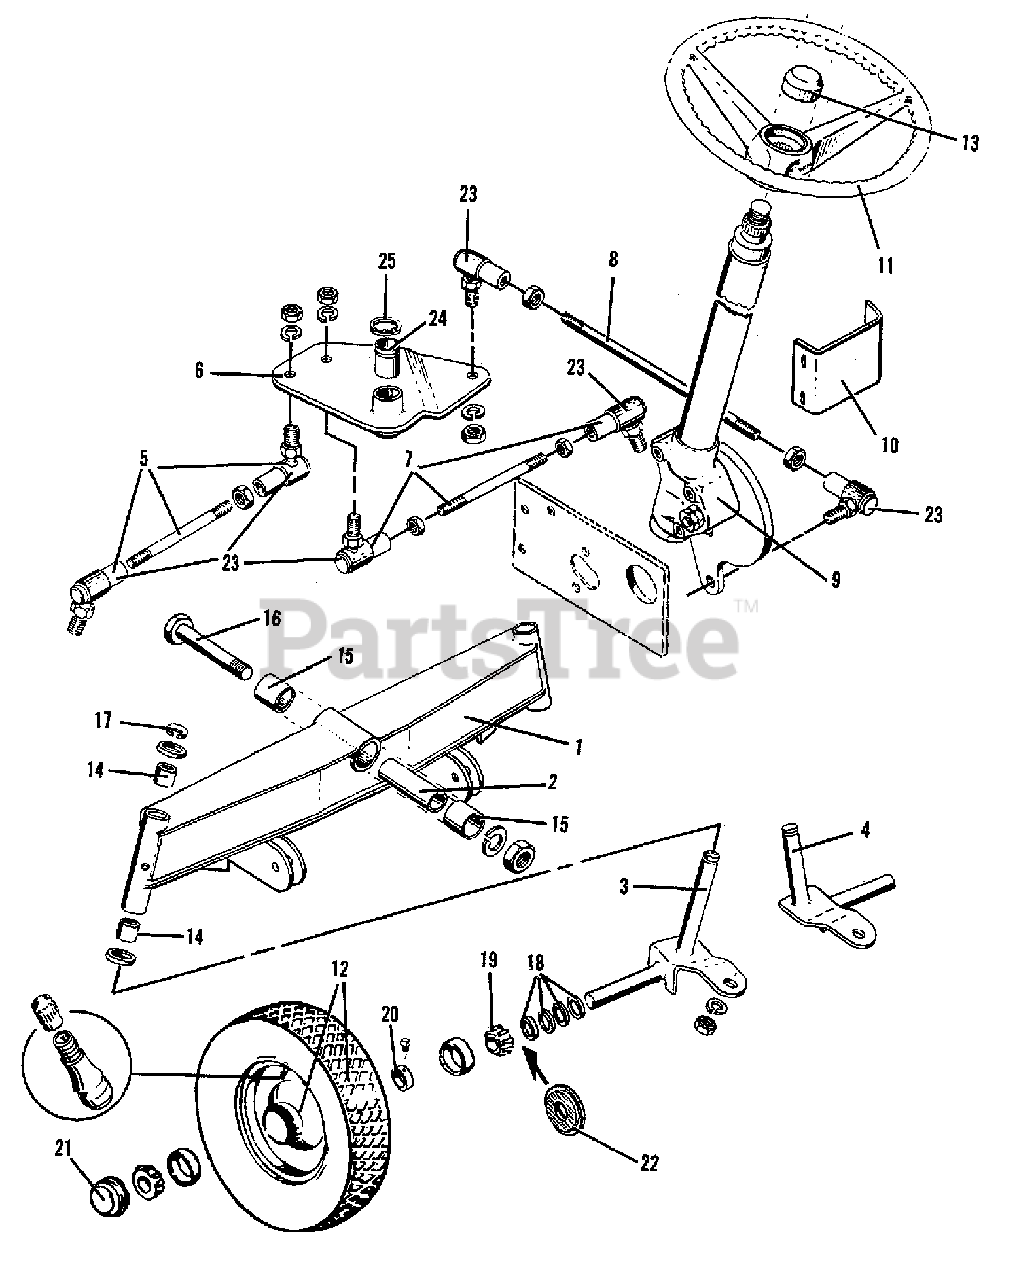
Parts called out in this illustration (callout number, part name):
1	AXLE ASSEMBLY, Front (Includes Item 15)
1	FITTING, Lube (Packaging Of 10)
2	SLEEVE, Axle
2	LOCKWASHER, 3/4
2	NUT, 3/4 NC
3	SPINDLE ASSEMBLY, L.H.
3	WASHER, Plain, 49/64 x 1-3/8 x 23 Ga.
4	SPINDLE ASSEMBLY, R.H.
4	WASHER, Plain, 49/64 x 1-3/8 x 23 Ga.
5	LINK ASSEMBLY, Drag (L.H.) (Includes 2 of Item 31)
5	NUT, Jam, 1/2NF
5	LOCKWASHER, 1/2
6	CRANK ASSEMBLY, Bell
6	WASHER, Plain 1-1/64 x 1-5/8 x 12 Ga.
7	LINK ASSEMBLY, Drag (R.H.) (Includes 2 of Item 31)
7	NUT, Jam, 1/2NF
7	LOCKWASHER, 1/2
7	NUT, 1/2 NF
8	NUT, Jam, 1/2NF
8	LOCKWASHER, 1/2
8	NUT, 1/2 NF
9	*
9	CAPSCREW, 3/8 NC x 3/4
9	LOCKWASHER, 3/8
10	BRACE, Steering Gear
10	CAPSCREW, 3/8 NC x 1
10	LOCKWASHER, 3/8
10	NUT, 3/8 NC
10	WASHER, Plain, 13/32 x 21/32 x 1/16
11	WHEEL, Steering
12	WHEEL ASSEMBLY, (F/16 x 6.50-8 Tubeless Type Tire)
12	WHEEL ASSEMBLY, (F/4.80.4.00=8 Tube Type Tire)
12	CUP, Bearing
12	VALVE ASSEMBLY, Stem & Cap (Tubeless Tire)
12	TUBE, Tire (F/16 x 6.50-8 Tubeless Type Repair)
12	TUBE, Tire (F/4.80.4.00=8 Tube Type Tire)
13	CAP, Steering Wheel
15	BEARING, Sleeve
16	CAPSCREW, 3/4NC x 4-1/2 (Special Thread Length
17	RING, Retaining
19	BEARING ASSEMBLY, Cone Roller
20	COLLAR ASSEMBLY, Set (Includes SETSCREW)
20	SETSCREW, 5/16NC x 5/16 Socket Head)
23	JOIN ASSEMBLY, Ball
24	BEARING, Sleeve
25	RING, Retaining (External)
